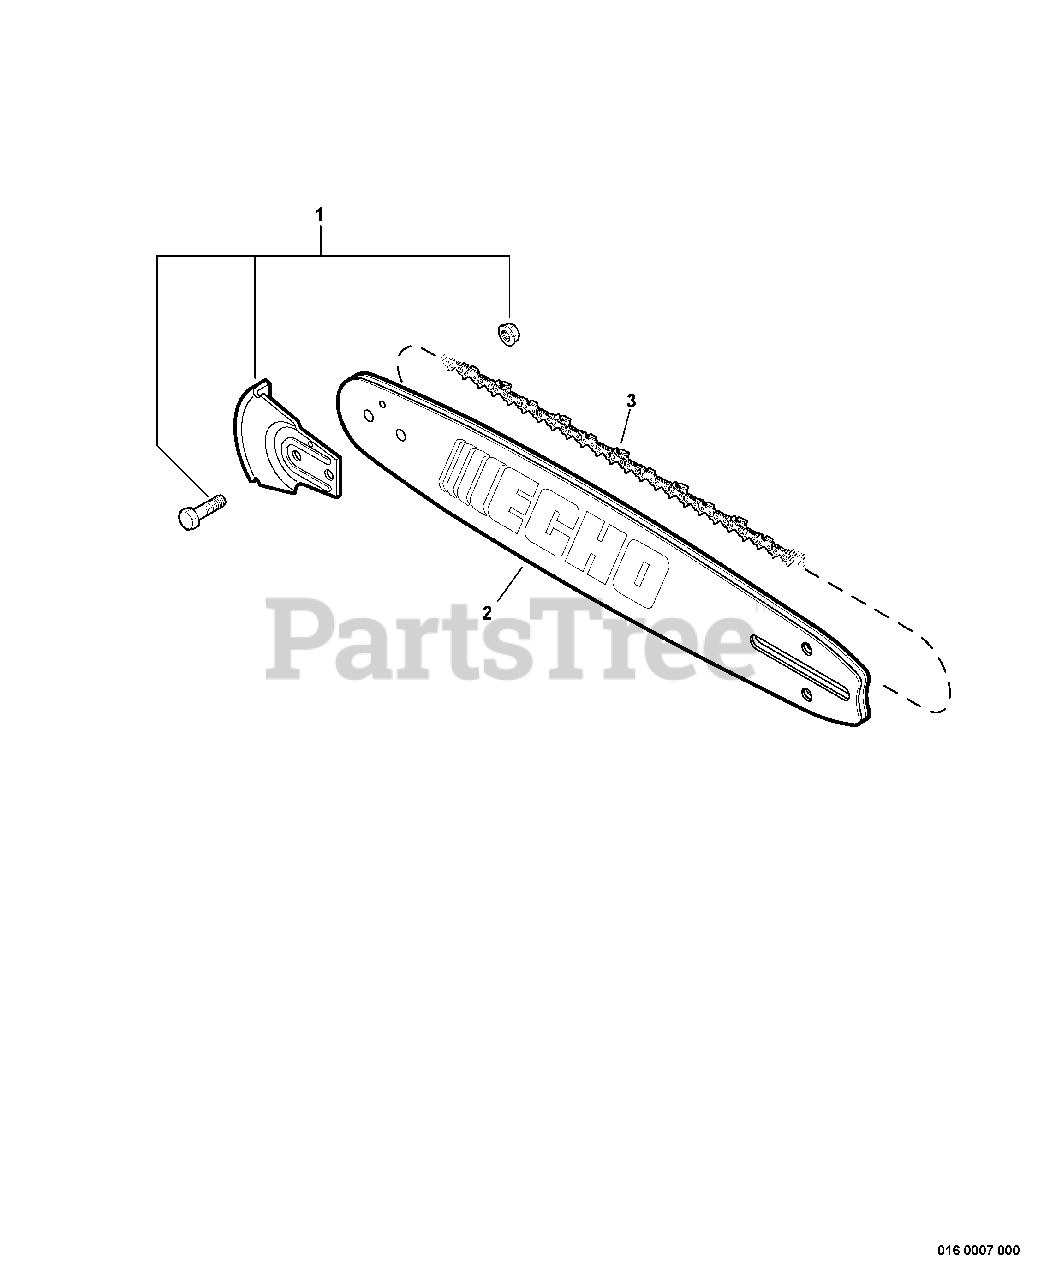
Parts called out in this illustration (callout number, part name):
1	KICK GUARD KIT
2	GUIDE BAR - 18" -- DOUBLE GUARD
3	SAWING CHAIN - 18" -- PRO GUARD
